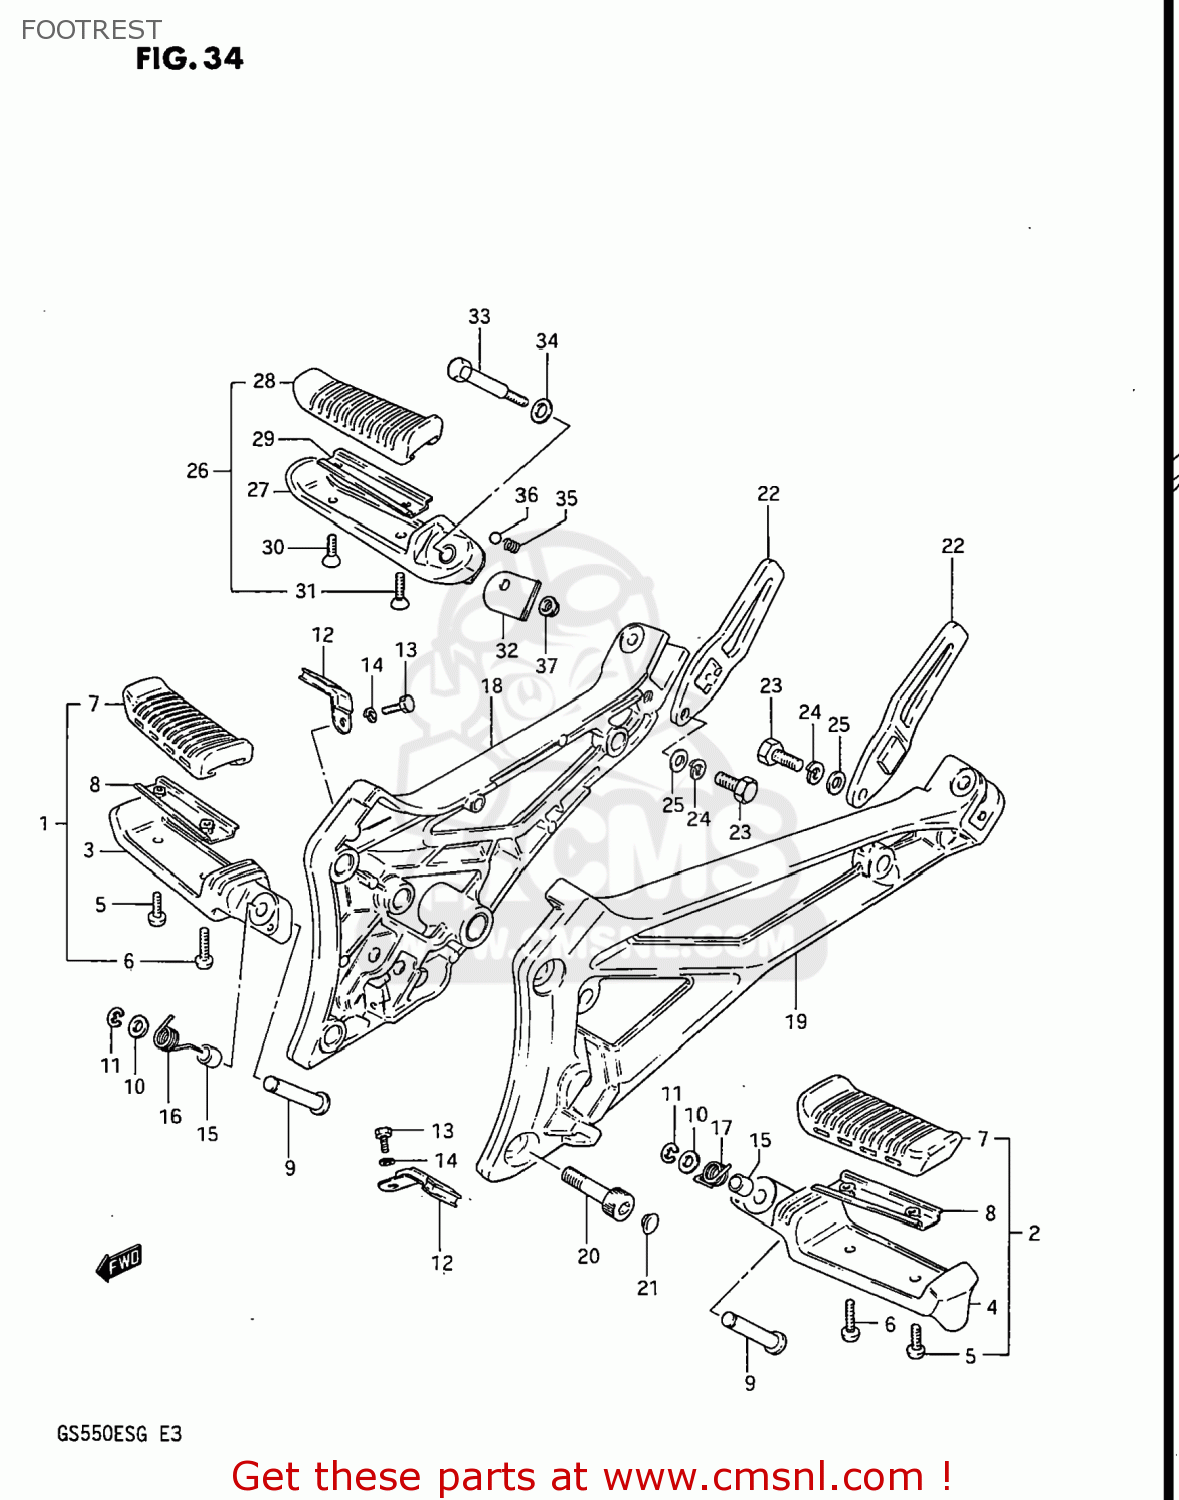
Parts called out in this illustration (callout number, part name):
1	FOOTREST ASSEMBLY,FRONT,RIGHT
2	FOOTREST ASSEMBLY,FRONT,LEFT
3	BAR,FRONT FOOTREST
4	FOOTREST,FRONT,LEFT
5	SCREW
6	SCREW
7	RUBBER,FOOTREST
8	PLATE,FR FOOTREST RUBBER
9	PIN
10	WASHER
11	E RING 6MM
12	CUSHION,FR FOOTREST
13	BOLT 5X10
14	LOCK WASHER
15	BUSHING
16	SPRING
17	SPRING
18	BRACKET,MUFFLER,RIGHT
19	BRACKET,MUFFLER,LEFT
20	BOLT 10X27
21	CAP
22	GUIDE,REAR FOOT
23	BOLT,8X16
24	LOCK WASHER
25	WASHER
26	FOOTREST ASSY,PILLION,R
27	BAR,PILLION FOOTREST,LEFT
28	RUBBER,RR FOOTREST
29	PLATE,RUBBER STOPPER
30	SCREW 5X12
31	SCREW 5X16
32	PLATE,SPRING STOP,R
33	BOLT
34	WASHER
35	SPRING
36	BALL
37	NUT
